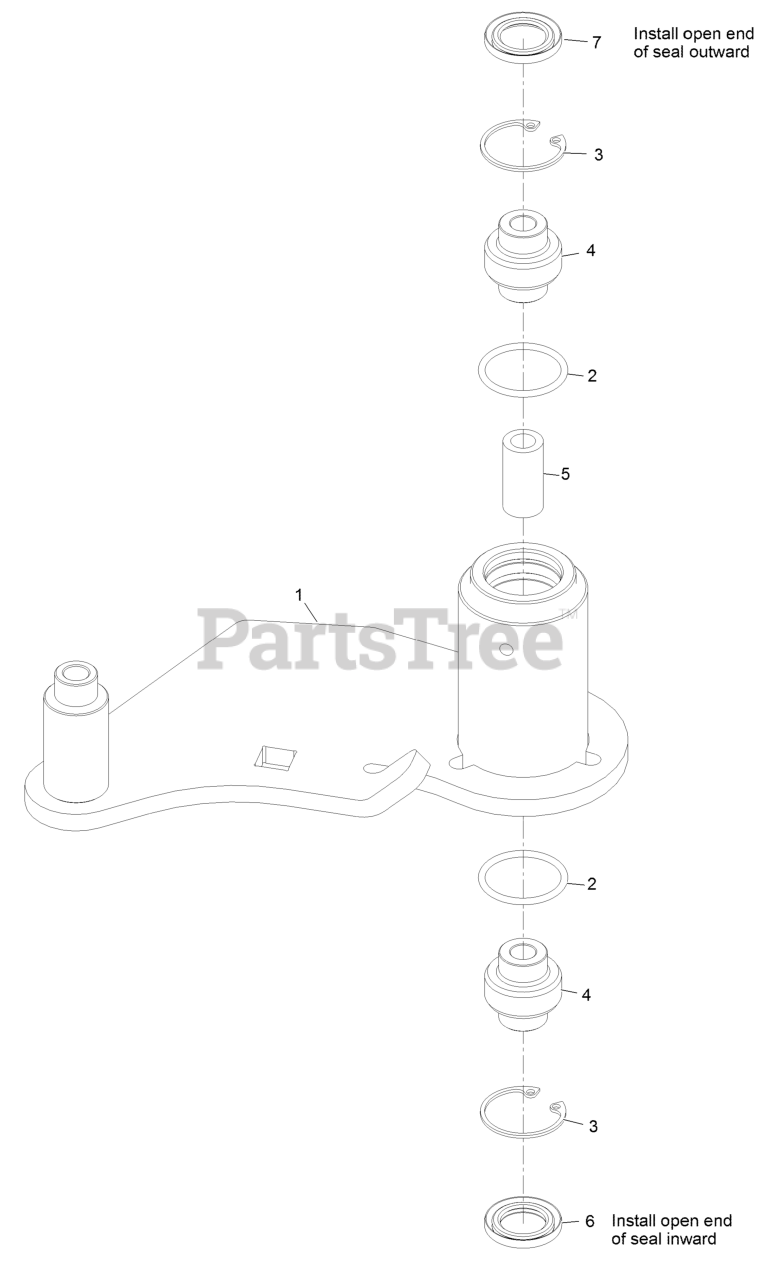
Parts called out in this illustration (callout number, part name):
1	Deck Idler [red]
3	RING-SNAP
4	BEARING-SPHERICAL
6	SEAL-LIP, DOUBLE
7	SEAL-LIP, SINGLE
